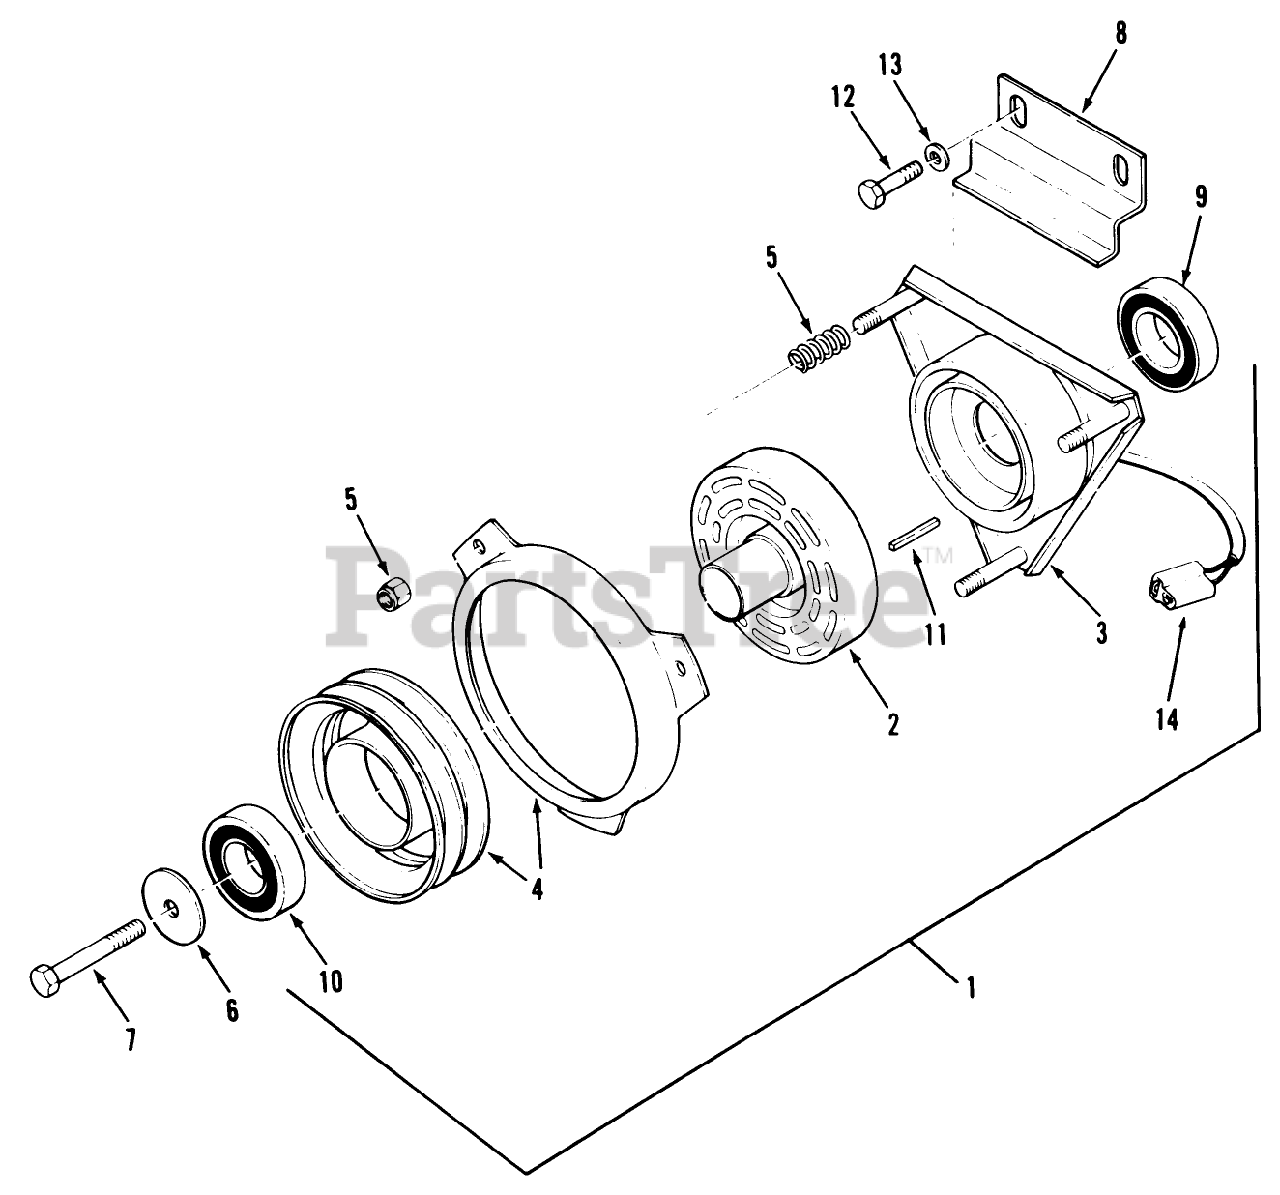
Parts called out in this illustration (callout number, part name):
1	Electric Clutch Complete (Includes items 2, 3, 4, 5, 9, 10 & 14)
2	Rotor
3	Field (Includes item 9)
4	Armature and Pulley (Includes item 10)
5	Spring & Nuts
6	RETAINER-BEARING
7	Bolt 3/8-24 x -1/4
8	BRACKET-CLUTCH B
9	BEARING-FIELD ASS'Y
10	Bearing
11	KEY-SQUARE
12	Bolt
13	Washer
14	CONNECTOR BODY B
